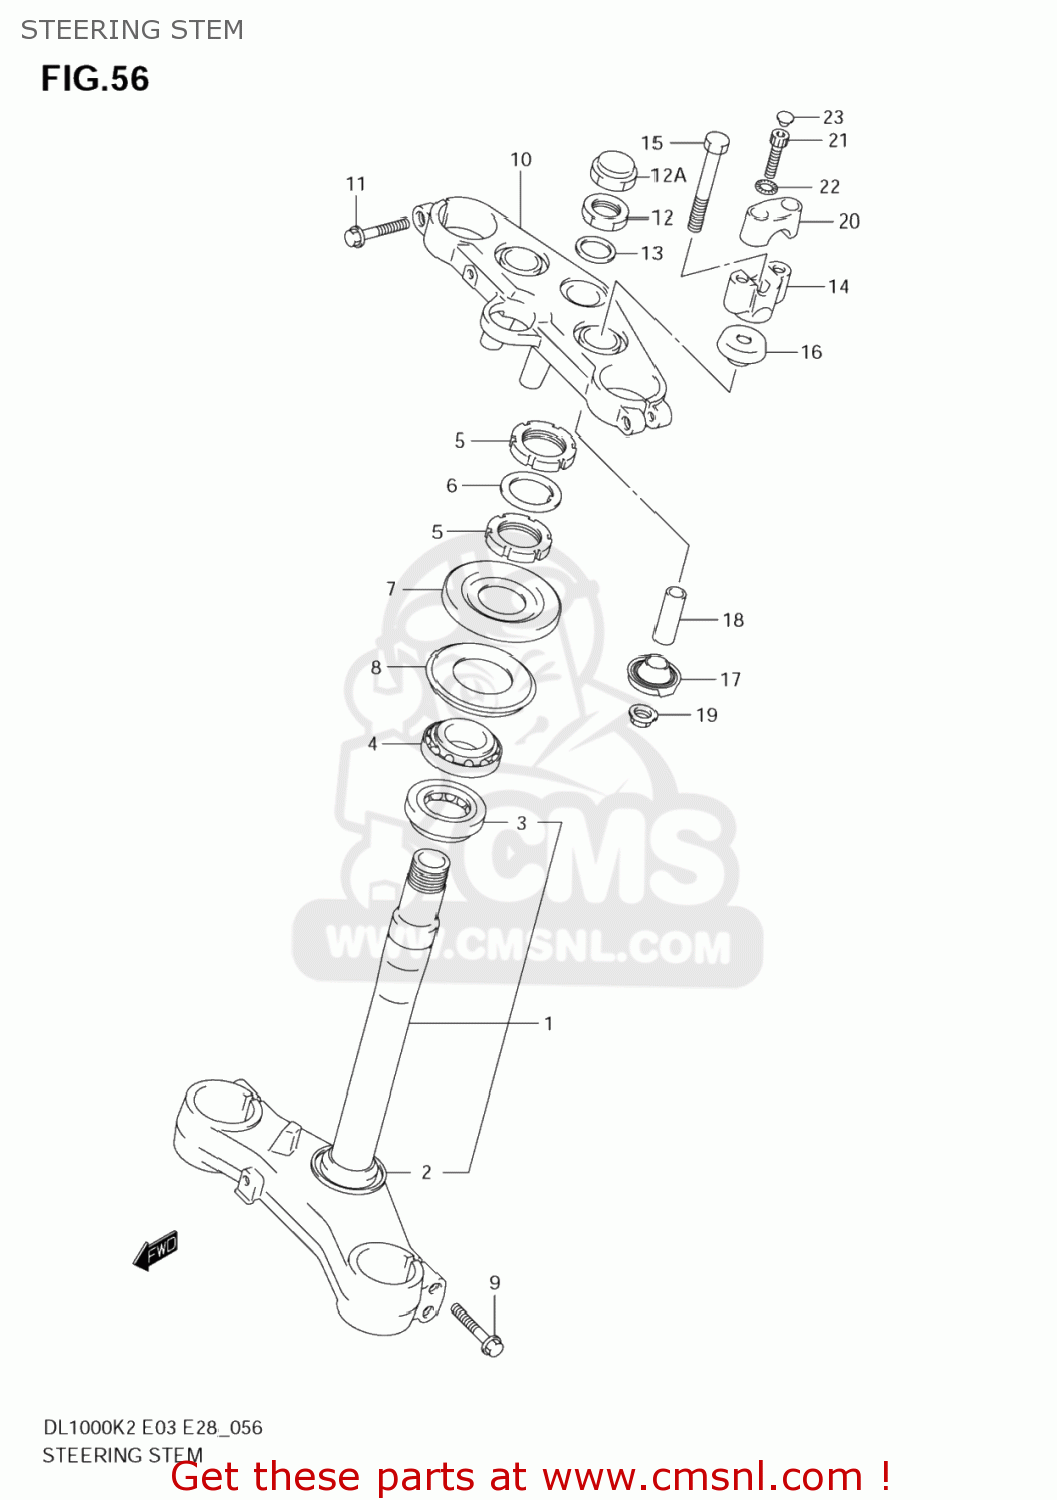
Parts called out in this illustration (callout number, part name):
1	STEM,STEERING
2	SEAL,STEERING LWR
3	BEARING(30X55X17)
4	BEARING(30X55X17)
5	NUT,STEERING STEM
6	WASHER,STEERING STEM
7	COVER,STEERING UPR
8	SEAL,STEERING LWR
9	BOLT
10	HEAD,STEERING STEM
11	BOLT
12	NUT
12A	NUT
13	WASHER
14	HOLDER,HANDLE UNDER
15	BOLT,HANDLE HOLDER(10X70)
16	CUSHION,RUBBER UPR
17	RUBBER,LWR
18	SPACER
19	NUT
20	HOLDER,HANDLE UPR
21	BOLT
22	WASHER
23	CAP(OD:11)
